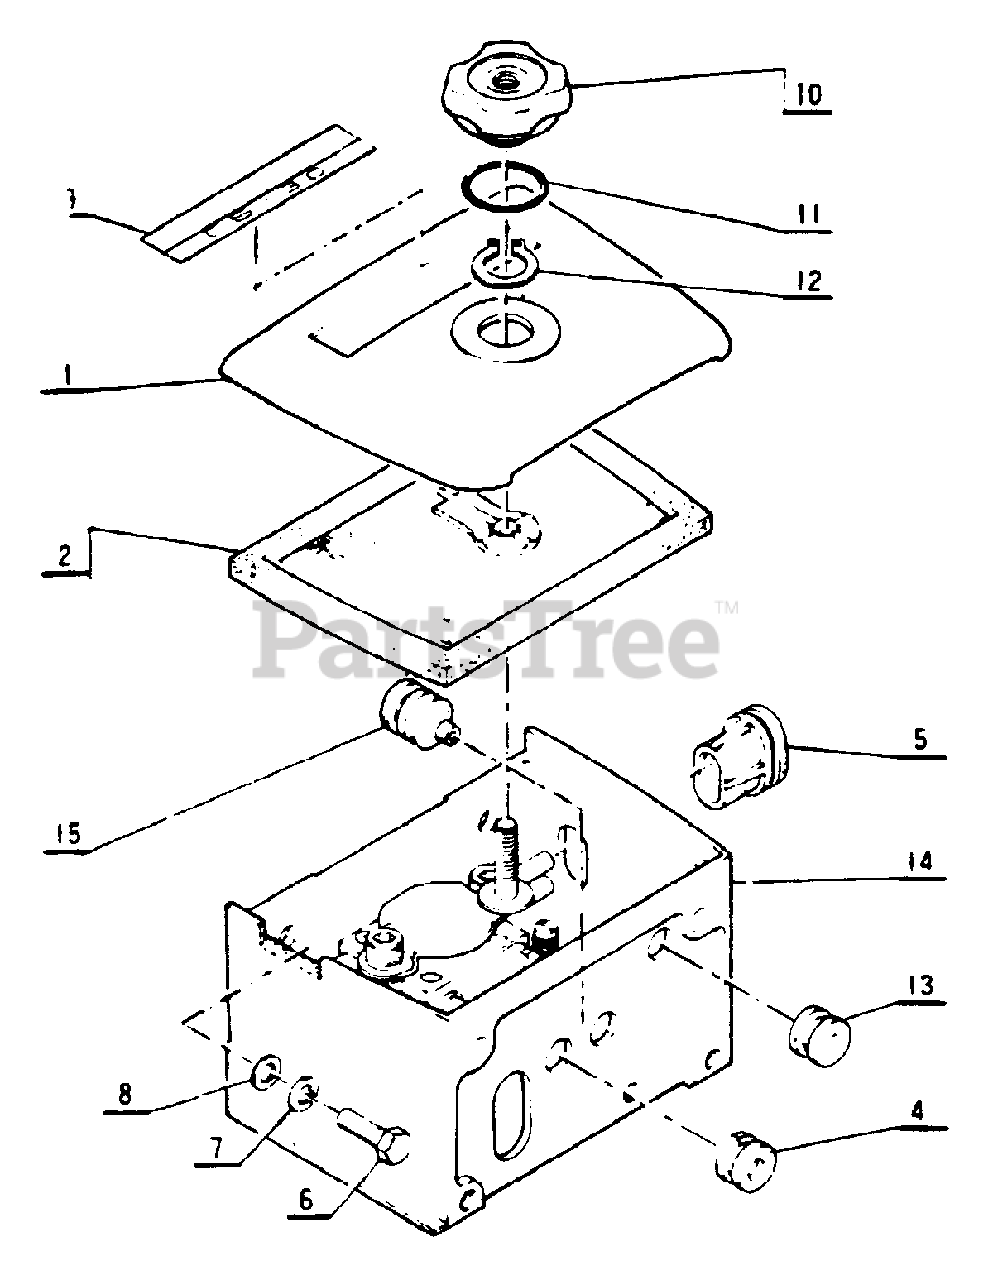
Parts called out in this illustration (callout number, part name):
1	COVER, AIR FILTER
2	FILTER, AIR
5	GROMMET
6	BOLT 5×12
7	WASHER, SPRING 5
8	WASHER, FLAT 5.5×10×0.8
9	NAME LABEL
10	WINGNUT
11	O-RING
13	GROMMET, RUBBER
14	CASE, CARBURETOR
